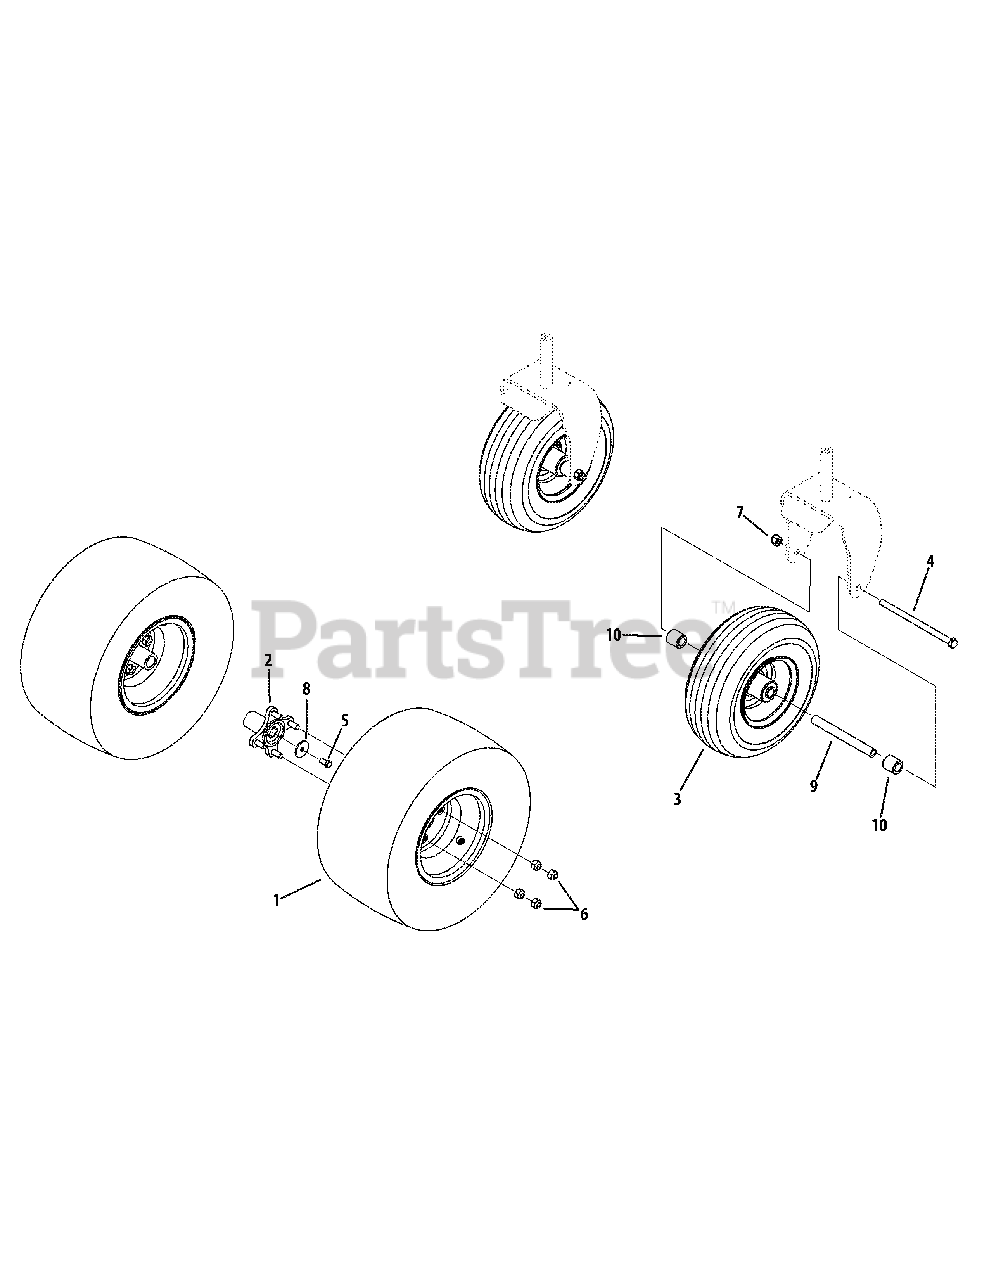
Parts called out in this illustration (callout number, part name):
1	Wheel Assy., 20 x 10.00 x 10 (60")
2	Wheel Hub Assembly (60" only)
4	Hex Screw, 1/2-13 x 8.5
5	Hex Screw, 3/8-16 x .750 (60" Only)
6	Lug Nut, 7/16-14
7	Hex Lock Nut, 1/2-13
8	Flat Washer, .390 x 1.500 x .134 (60" Only)
9	Spacer, .51 x .75 x 1.25
10	Hub, .76 x 1.23 x 1.25
